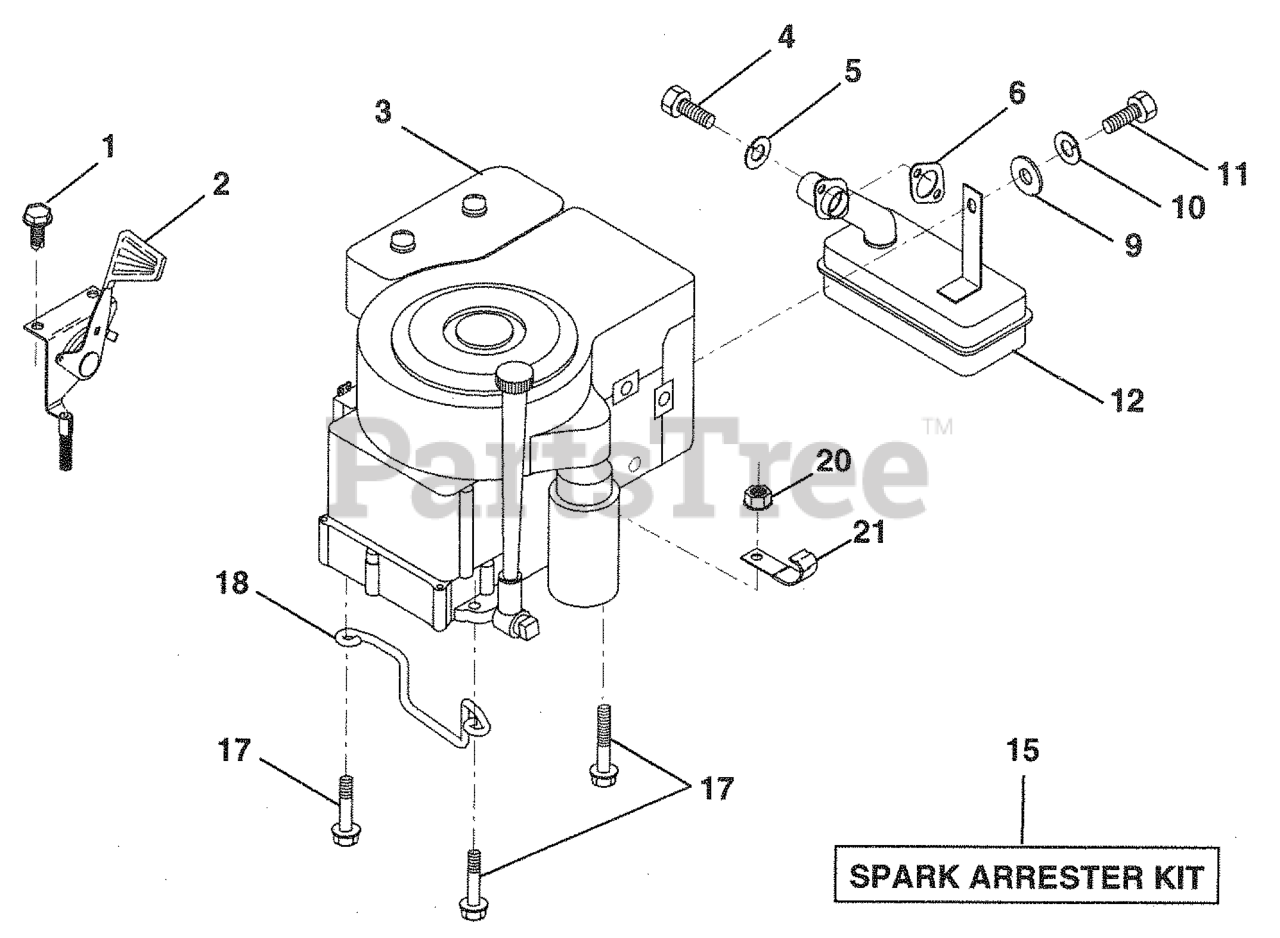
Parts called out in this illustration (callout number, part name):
1	SCREW
2	CONTROL.TH/CH.RH.BLK.FLG.26
4	SCREW
5	WASHER.LOCK.HVY.HLCL.SPR.5/16
6	GASKET ENGINE
9	WASHER
10	LOCKWASHER
11	Bolt, Hex Fin. 1/4-20 UNC x 3/4
12	MUFFLER.SINGLE.B&S.12HP
15	KIT.SPARK ARRESTOR 794945 B&S
17	Screw, Hex Washer Head, Thdrol. 3/8-16 x 1-1/2
18	Keeper, Ground Drive Beit
20	Nut, Keps 3/8 - 16
21	CLIP T
